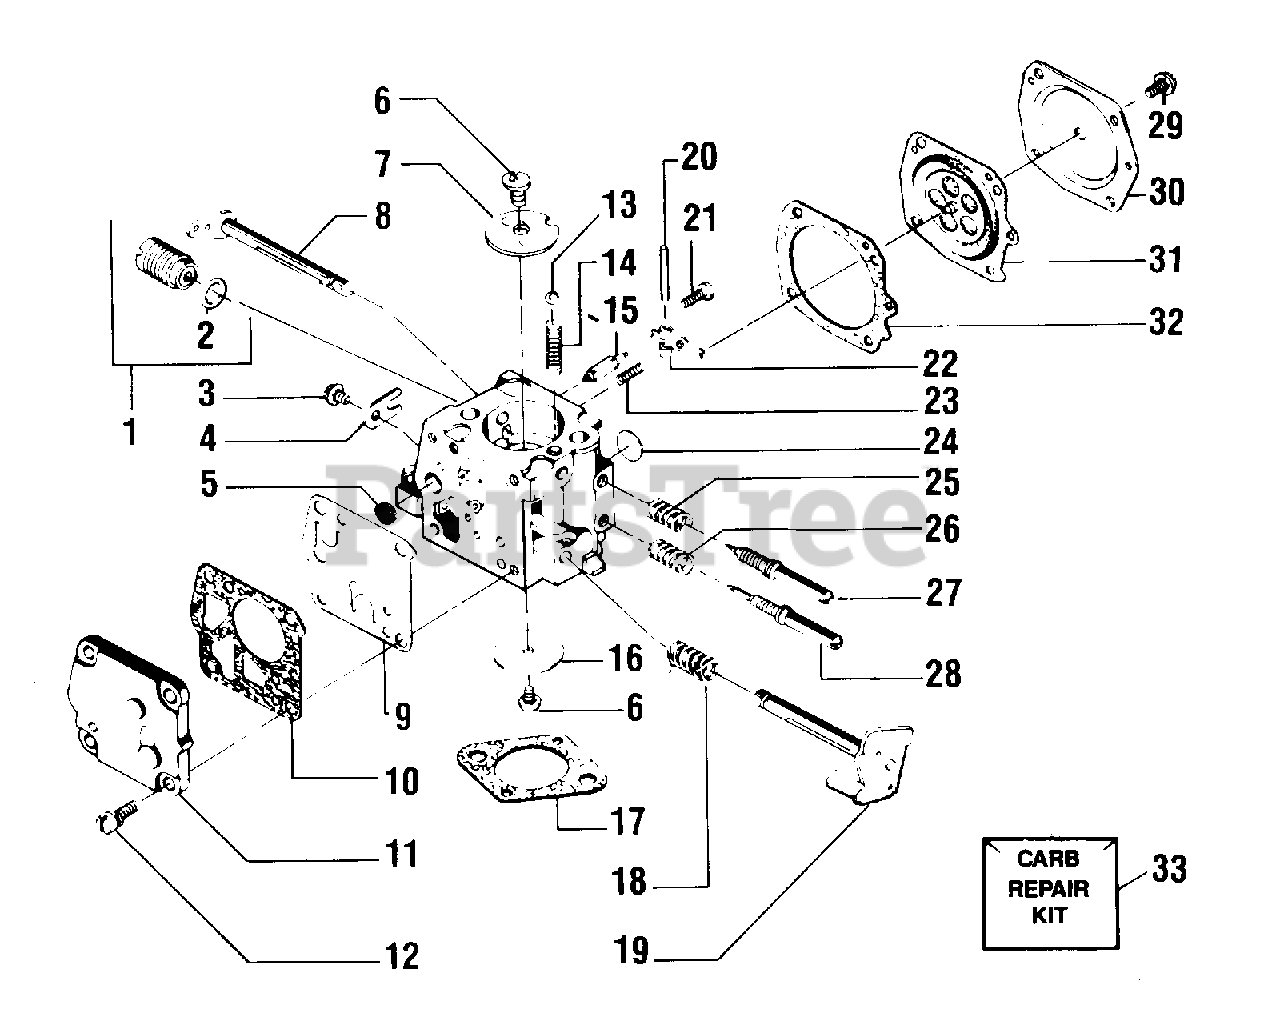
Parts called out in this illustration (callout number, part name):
1	Governor Valve Assembly (Incl. #2)
2	Gasket - Governor Valve
3	Screw - Throttle Shaft Clip Retainer
4	Clip - Throttle Shaft
5	Inlet Screen
6	Shutter Screw & Lockwasher
7	Choke Shutter
8	Choke Shaft & Lever
9	Fuel Pump Diaphragm
10	Fuel Pump Gasket
11	Fuel Pump Cover
12	Screw and Lockwasher - Fuel Pump Cover Retainer
13	Choke Friction Ball
14	Choke Friction Spring
15	Needle - Inlet
16	Throttle Shutter
18	Spring - Throttle Shaft Return
19	Throttle Shaft & Lever
20	Pin - Inlet Pinion
21	Screw - Inlet Pinion Pin Retainer
22	Lever - Inlet Control
23	Spring - Inlet Tension
24	Plug - Body Channel Welch (Large)
25	Spring - High Speed Mixture Spring (Blue)
26	Spring - Idle Mixture Screw (Yellow)
27	HIGH SPEED SCREW
28	Screw - Idle Mixture
29	Screw & Lockwasher - Diaphragm
30	Cover - Diaphragm (Dana part number)
31	Diaphragm
32	Gasket - Diaphragm
33	Carb. - Repair Parts Kit (Inc. 5,9,10,15,17, 22,24,31,32)
